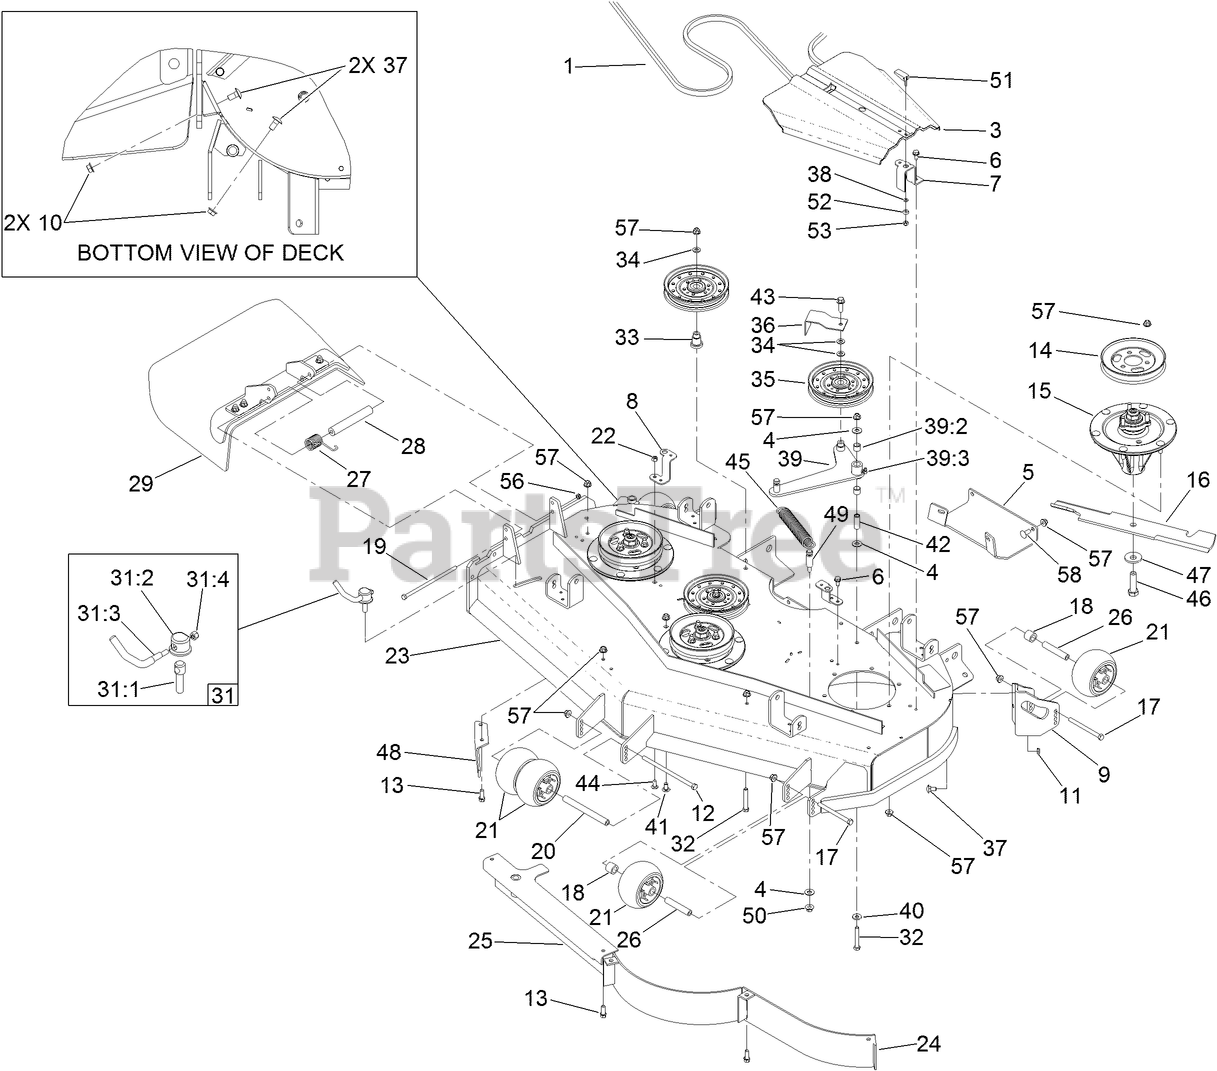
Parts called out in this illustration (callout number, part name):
1	BELT-V
3	COVER-BELT
4	WASHER-FLAT
5	PLATE-SKID
6	SCREW-HWHTF
7	BRACKET-COVER
8	BRACKET-COVER, TALL
9	MOUNT-WHEEL, LH
10	NUT-HHF, WHIZ
12	SCREW-HH
14	PULLEY
15	SPINDLE ASM
16	BLADE-18IN, HI FLOW
17	SCREW-HH
18	TUBE-SPACER
19	SCREW-HH
20	SPACER-WHEEL
21	ROLLER-SCALP, ANTI
22	NUT-LOCK, NI
23	DECK DECAL ASM
26	TUBE-SPANNER
27	SPRING-TORSION
28	SPACER
29	RUBBER DEFLECTOR ASM
31	LEVER ASM
31:1	SCREW-LOCK
31:2	CAP-LOCK
31:4	NUT-LOCK, NI
32	SCREW-HH
33	MOUNT-PULLEY
34	WASHER-FLAT
36	GUIDE-BELT
37	SCREW-HH
38	WASHER
39	DECK IDLER ARM ASM
39:2	SLEEVE-BEARING
39:3	FITTING-GREASE, 90 DEG
40	WASHER-BELLEVILLE
41	SCREW-CARR
42	BUSHING
43	SCREW-HHF
44	SCREW-CARR
45	SPRING-EXTENSION
46	SCREW-BLADE
47	WASHER-BLADE BOLT, HEAVY
48	BAFFLE-DISCHARGE
49	PIN-THREADED, SPRING ANCHOR
50	NUT-HF
51	HANDLE-LATCH, SWELL
52	BUSHING-LATCH, SWELL
53	NUT-LOCK, HH
56	NUT-LOCK, NI
57	NUT-HF, NI
58	SCREW-CARR
